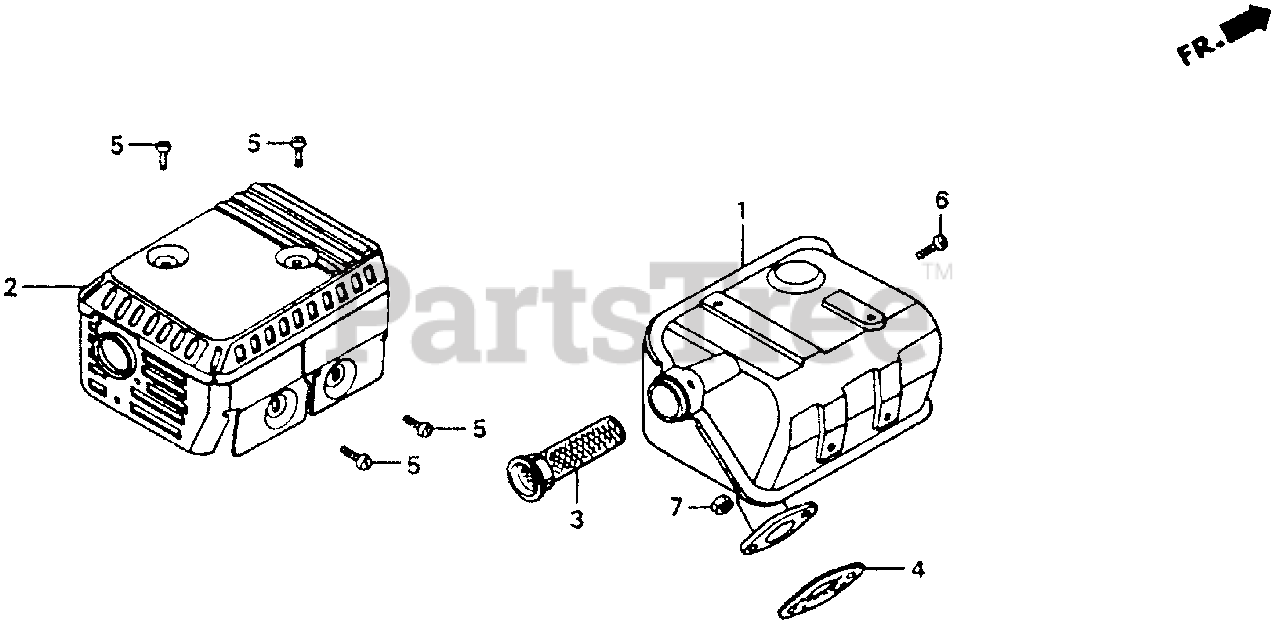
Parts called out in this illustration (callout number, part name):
1	MUFFLER (STD)
1	MUFFLER (ARRESTER) Use up to Engine SN 1870782.
1	MUFFLER (ARRESTER) Use from Engine SN 1870783.
2	PROTECTOR (UPPER)
2	PROTECTOR, MUFFLER (ALUMINIZED)
3	ARRESTER, SPARK
4	GASKET, MUFFLER
5	SCREW, TAPPING (5X8)
6	SCREW, TAPPING (4X6)
7	NUT, HEX. (8MM)
